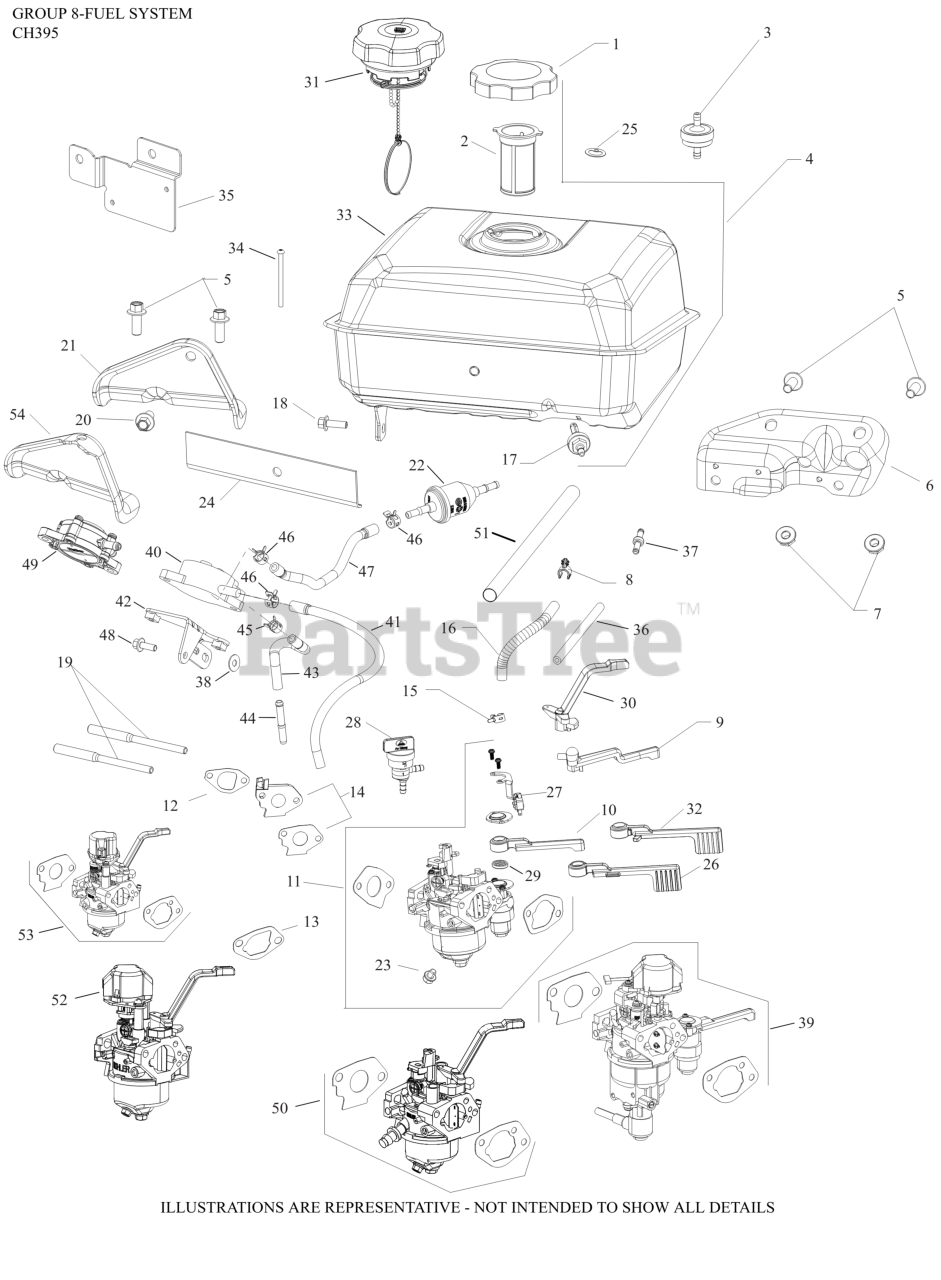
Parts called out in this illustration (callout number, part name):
5	SCREW, M8 X 20
11	KIT, CARBURETOR-USE 17 853 95-S
14	INSULATOR AND GASKET KIT
15	CLAMP, FUEL LINE
16	FUEL HOSE, LOW PERMEATION
16	LINE, FUEL (10"-CUT TO LENGTH)
19	STUD, INTAKE
22	FILTER,FUEL 75 MICRON (GRAVTY FEED)
30	LEVER, CHOKE
39	KIT, CARBURETOR COMPLETE
45	CLAMP, HOSE
NI	KIT, HIGH ALTITUDE (4,000-8,000 FT)
NI	KIT, HIGH ALTITUDE (ABOVE 8,000 FT.)
NI	KIT, CARBURETOR REPAIR
